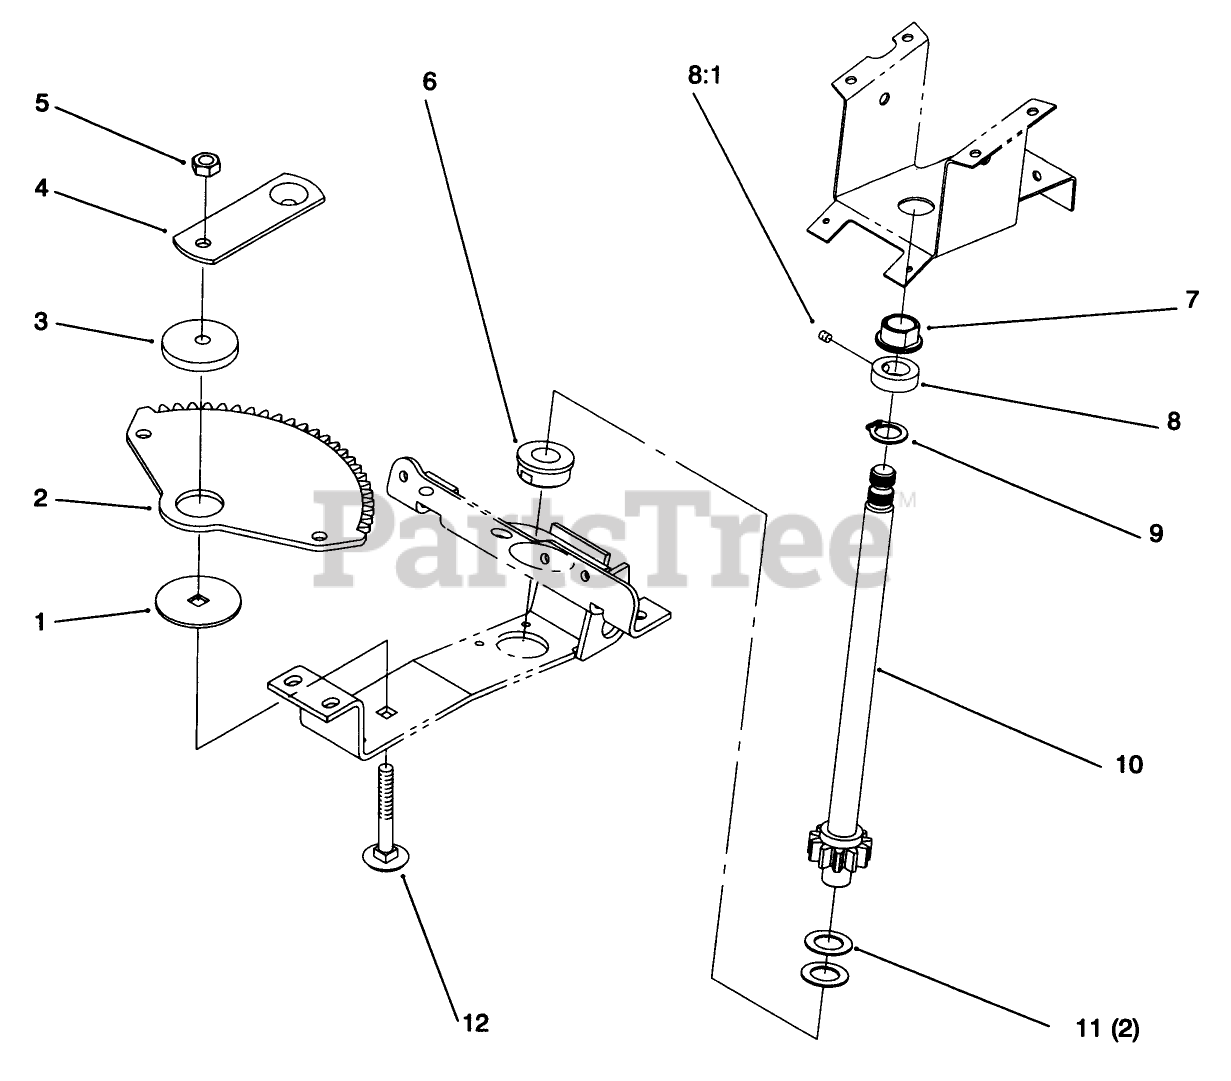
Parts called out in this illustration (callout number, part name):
1	WASHER-BEARING
3	BUSHING
5	NUT-HEX
6	BEARING-WHEEL
7	BEARING-FLANGED
8	COLLAR
8:1	SCREW-HSH
9	RING-RETAINING
10	SHAFT-STEERING, LOWER
11	WASHER
12	SCREW-CARR
